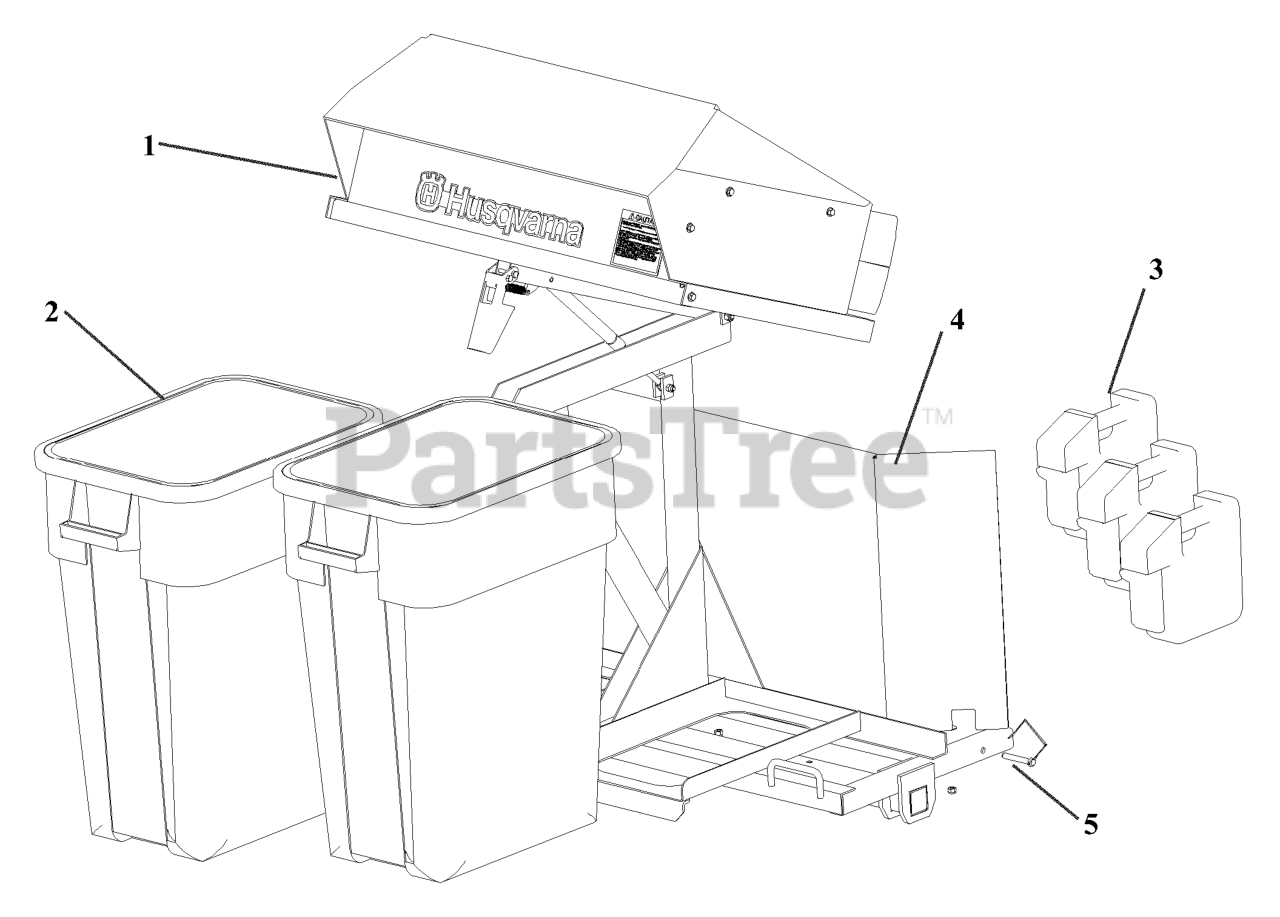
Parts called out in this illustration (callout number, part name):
1	FRAME/TOP ASSY
2	CONTAINER - 30 GAL/GREEN
3	FRONT WEIGHT PZ DFS
4	HEAT SHIELD
5	PIN-WIRE LOCK
